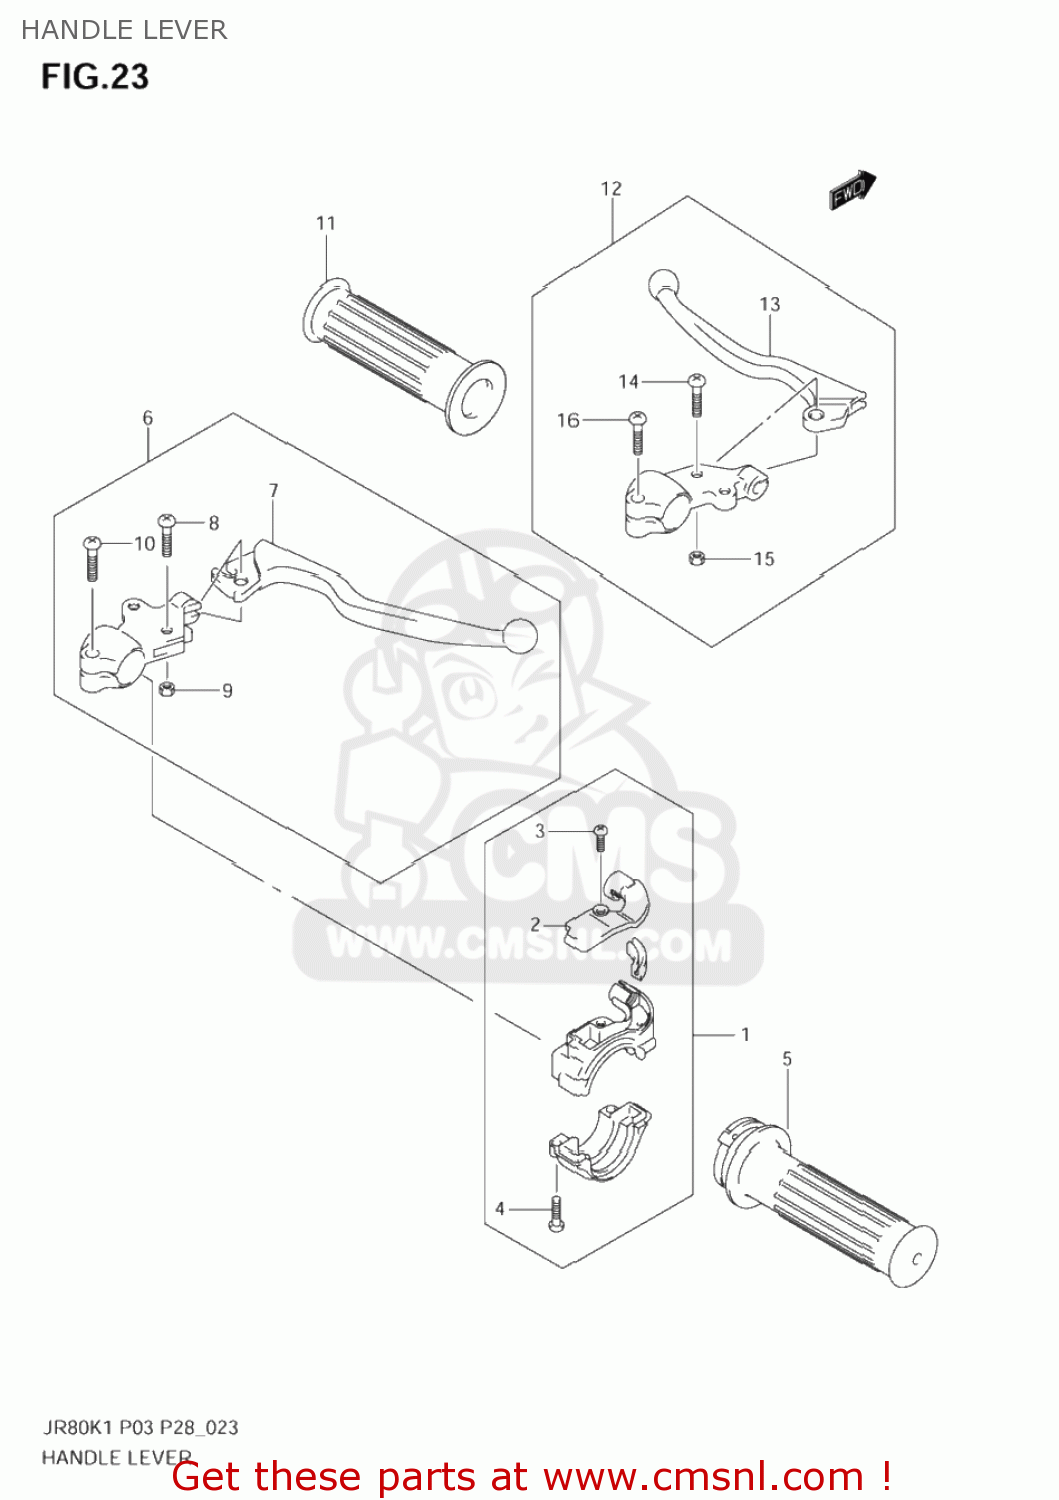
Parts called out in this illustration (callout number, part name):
1	CASE ASSY,THROTTLE
2	COVER,THROTTLE CASE
3	SCREW,UPPER
4	SCREW
5	GRIP,THROTTLE
6	LEVER ASSY,BRAKE
7	LEVER,BRAKE
8	SCREW
9	NUT
10	SCREW, 6X20
11	GRIP,L
12	LEVER ASSY,CLUTCH
13	LEVER,CLUTCH
14	SCREW
15	NUT
16	SCREW, 6X20
